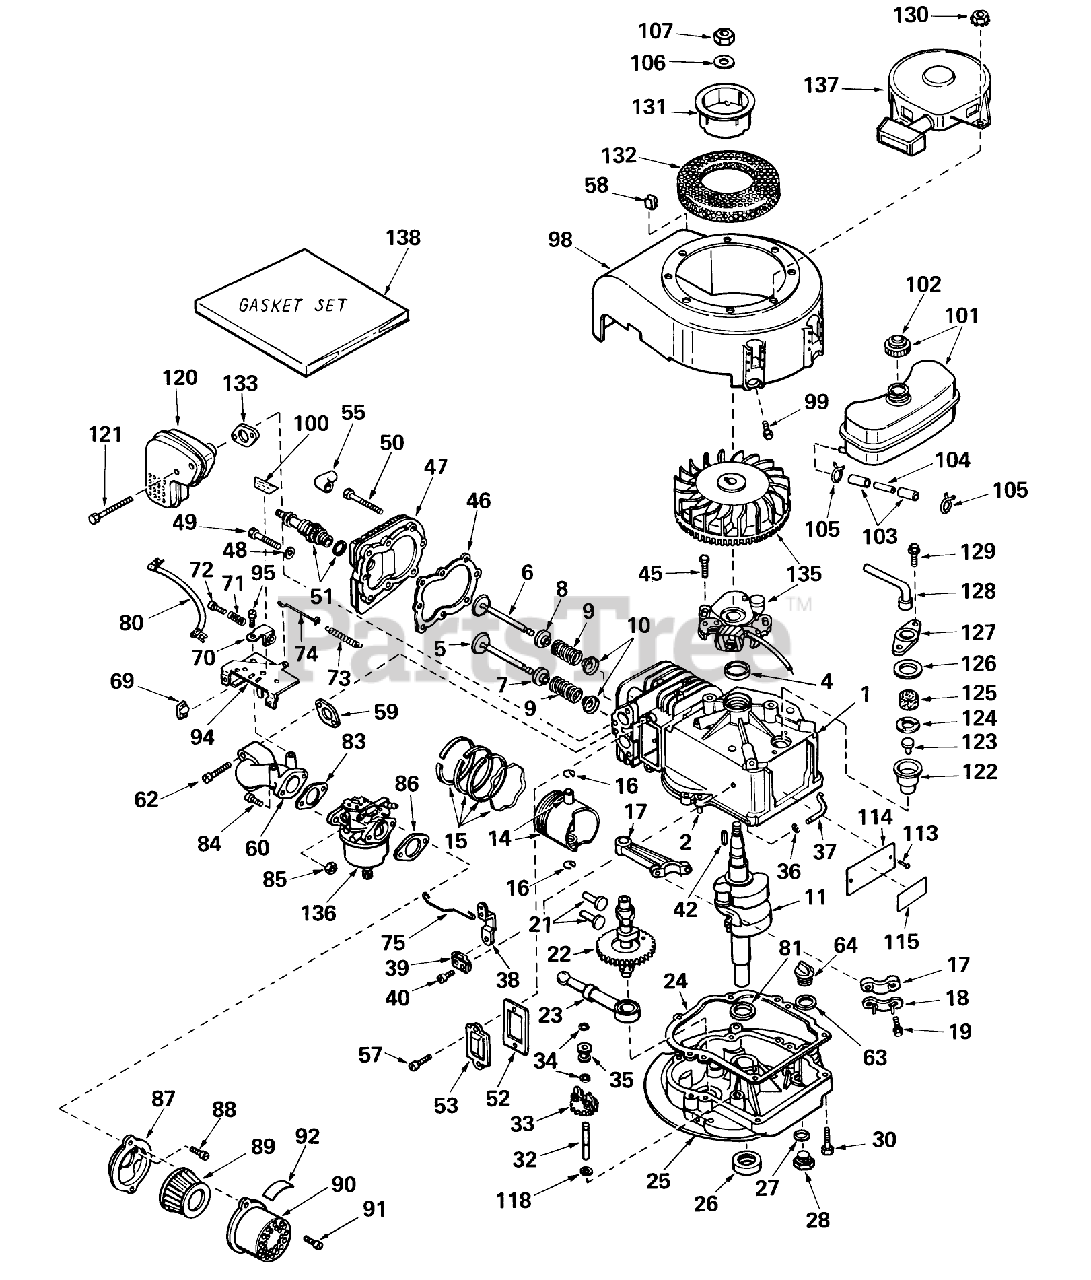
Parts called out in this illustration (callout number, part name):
1	Cylinder Assy. (Incl. Nos. 2 4)
2	Pin-Dowel
4	Seal-Oil
5	Valve, Intake (Standard) (Incl. Nos. 7, 9 10)
5	Valve, Intake (1/32" Oversize) (Incl. Nos. 7, 9 10)
6	Valve, Exhaust (Standard) (Incl. Nos. 8, 9 10)
6	Valve, Exhaust (1/32" Oversize) (Incl. Nos. 8, 9 10)
7	Cap-Upper Valve Spring
8	Cap, Upper Valve Spg (Exhaust)
9	Spring-Valve
10	Cap-Valve, Spring
11	Crankshaft
14	Piston Pin Assy. (Standard) (Incl. 2 of No. 16)
14	Piston Pin Assy. (.010 Oversize) (Incl. 2 of No. 16)
14	Piston Pin Assy. (.020 Oversize) (Incl. 2 of No. 16)
15	Ring Set-Piston Std.
15	Ring Set-Piston .010 oversize
15	Ring Set-Piston .020 oversize
16	Ring-Retaining, Piston Pin
17	Rod Assy., Connecting (Incl. Nos. 18 19)
18	Connecting Rod Bolt
19	Plate Lock
21	Lifter-Valve
22	Camshaft (Compr. Release)
23	Oil Pump ASM
24	Gasket, Mounting
25	Flange Assy., Mounting (Incl. #26, 27, 28 32)
26	Seal-Oil
27	Gasket-Oil Drain
28	Plug Oil Drain
30	Screw (1/4-20 x 1-1/4)
32	Shaft-Governor
33	Governor Gear ASM
34	Ring-Retaining
35	Spool-Governor
36	Washer-Flat
37	Rod, Governor (Incl. No. 36)
38	Governor Lever
39	Clamp-Lever, Governor
40	Screw
42	Key Flywheel
45	Screw
46	Oil Fill Tube
47	Head Cylinder
48	Washer
49	Screw
50	Screw Hex Hd. Cap
51	Plug, Spark (J17LM or equiv.)
52	Gasket-Breather
53	Cover-Valve
55	Cover-Spark Plug
57	Screw
58	51004 GIL ROTARY TI
59	Gasket, Intake
60	Pipe, Intake
62	Screw, Fil. Slotted Hd.Sems
63	Gasket
64	Plug-Fill, Oil
69	Knob-Control
70	Brachet, Control
71	Spring
72	Screw, Hex Hd.
73	Spring, Governor
74	Link Governor Spring
75	Link Governor
80	Wire, Ground
81	Washer-Thrust
83	Gasket
85	Nut and Lock Washer (1/4-28)
86	Gasket
87	Bracket
88	Screw (10-32 x 1/2)
89	Element
90	Body
91	Screw
92	Decal
94	Control Assy., Speed
95	Screw (10-24 x 9/16)
98	Housing, Blower
99	Screw (1/4-20x19/32)
100	Decal
101	Tank Assy., Fuel (Incl. No. 102)
102	Cap, Fuel
103	Line-Fuel (8.62)
104	Line, Fuel
105	Clamp-Line, Fuel
106	Washer-Spring
107	Hex Nut
113	Stud
114	IDENTIFICATION PLATE
115	480B GIL SNWTHWR O/
118	Washer-Flat
120	Muffler
121	Screw-Fil. Hd.
122	Body Breather Tube
123	Valve Check
124	2000A37 WIZARD ROTA
125	Element-Breather
126	Gasket-Breather
127	Cover Breather
128	Tube, Breather
129	Screw, Hex Hd. w/Conical
130	Nut and Lock Washer (1/4-28)
131	Cup, Starter
132	Screen-Starter
133	Gasket-Exhaust
135	Magneto
136	Carburetor
137	Starter, Rewind
138	Gasket Set
